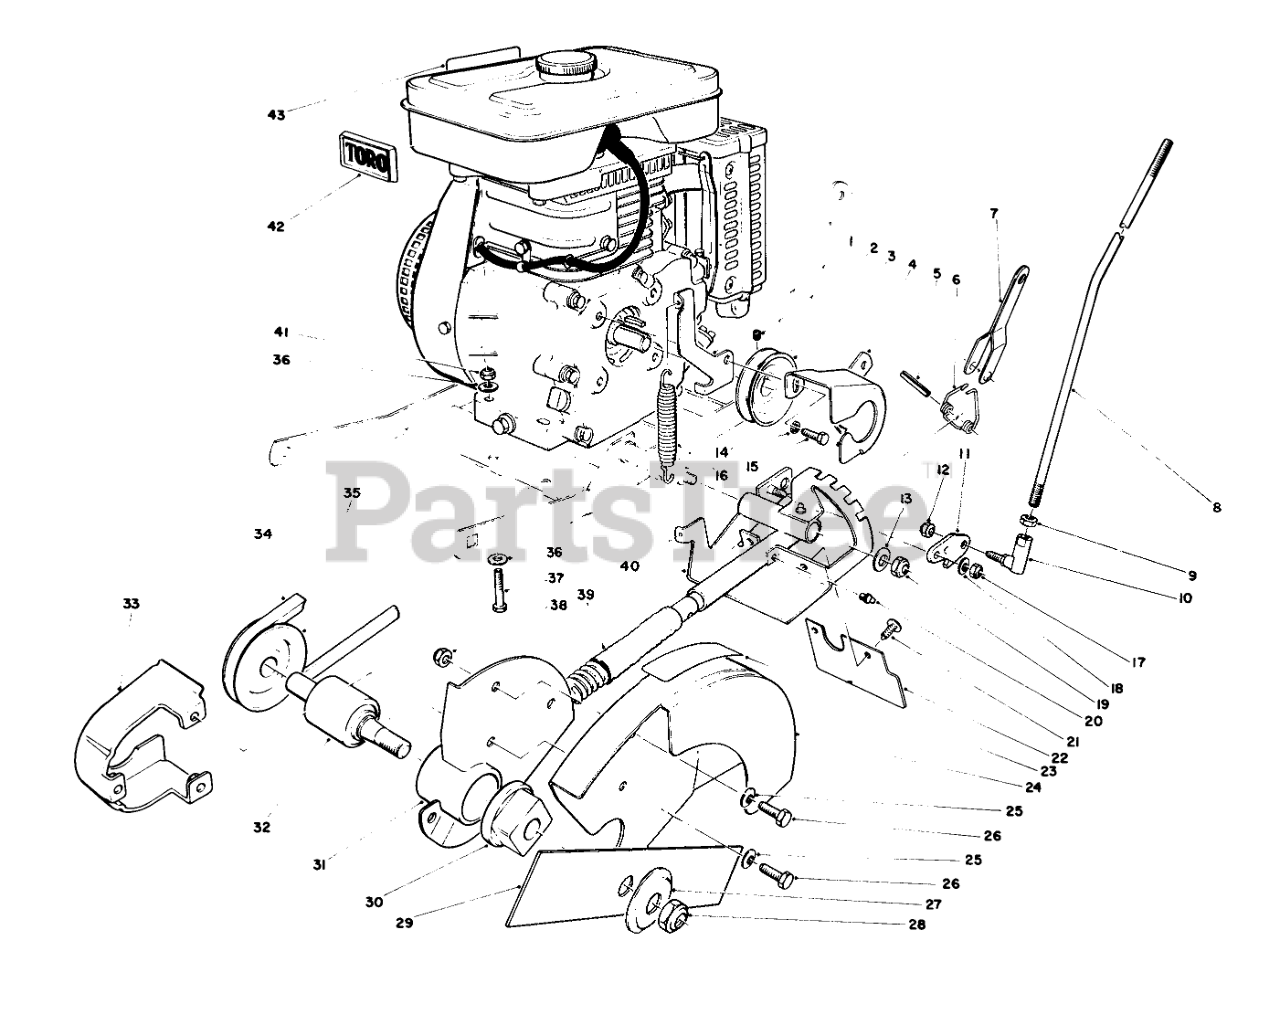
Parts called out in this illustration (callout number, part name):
1	SPRING BRKT R
2	SCREW-SET
3	PULLEY (3.5 HP)
4	ENG. PULLEY GUARD
5	PIN-ROLL
6	TORSION SPRING
7	LEVER WA R
8	Rod-Lower
9	NUT-HJ
10	BALL JOINT
11	LEVER LOCK WA
12	NUT-LOCK
13	WASHER-PLAIN
14	WASHER-LOCK
15	SCREW-HH
16	EXT. SPRING
17	NUT-LOCK, NI
18	WASHER-FLAT
19	NUT-LOCK, NI
20	FITTING-GREASE
21	PANEL FASTENER
22	RUBBER GUARD
23	BLADE WARNING DECAL
24	Blade Guard Assembly
25	WASHER-BELLEVILLE
26	SCREW-HWHTF
27	WASHER-BELLEVILLE
28	NUT-HEX
29	Blade-10"
30	BRG SHIELD
31	HUB ASM
32	Spindle Assembly
33	PULLEY GUARD WA
34	V-BELT
35	PULLEY-SPINDLE ASM
36	WASHER-PLAIN
37	SCREW-HH
38	NUT-HEX
39	SPRING & BELLOW ASM
40	PIVOT WA
41	NUT-LOCK, NI
42	TORO LOGO PLT
43	Decal-Instruction
